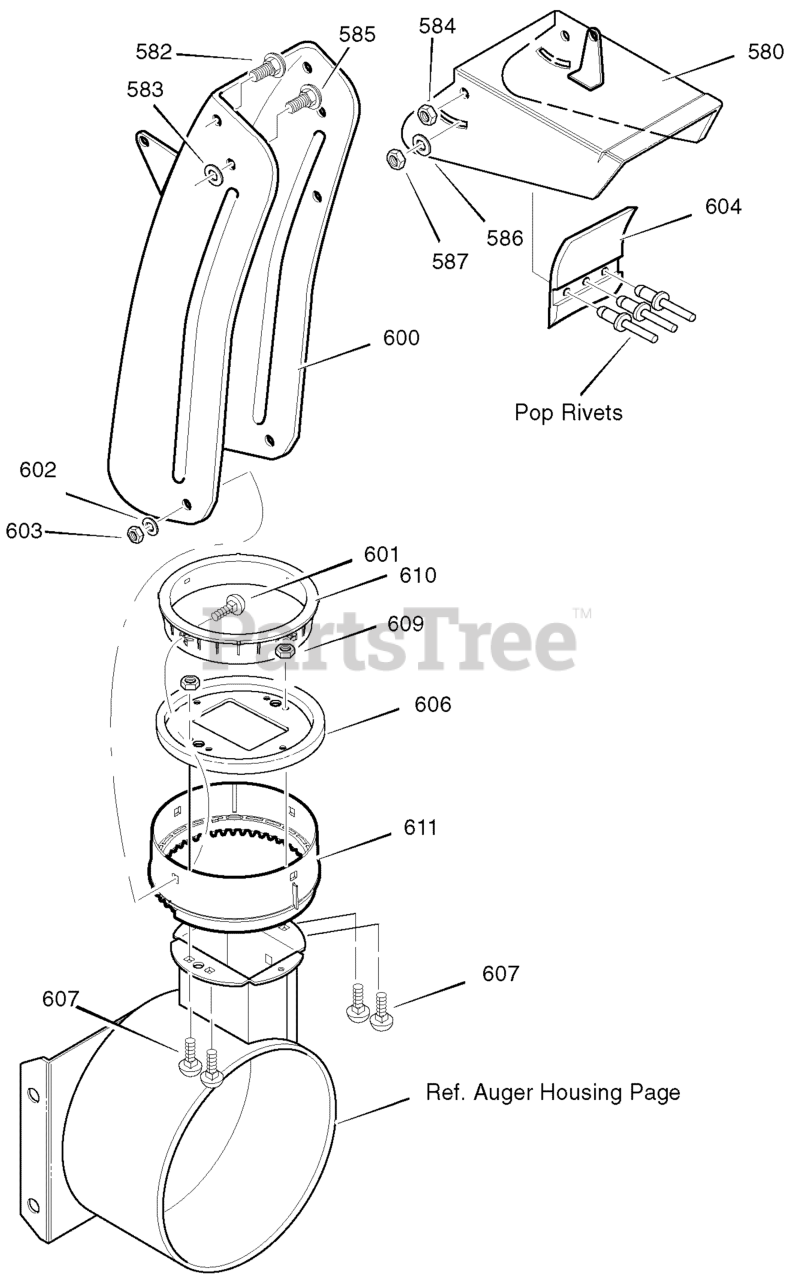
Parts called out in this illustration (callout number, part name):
580	CHUTE, UPPER W/REMOTE
582	SCREW, 5/16-18 X.75
584	NUT
585	SCREW, 5/16-18 X.75
586	PLASTIC WASHER
587	NUT
600	CHUTE, LOWER W/REMOTE
601	BOLT
602	WASHER, FLAT
603	NUT
606	CHUTE COLLAR
610	RETAINER, RING INNER
611	RETAINER, RING OUTER
